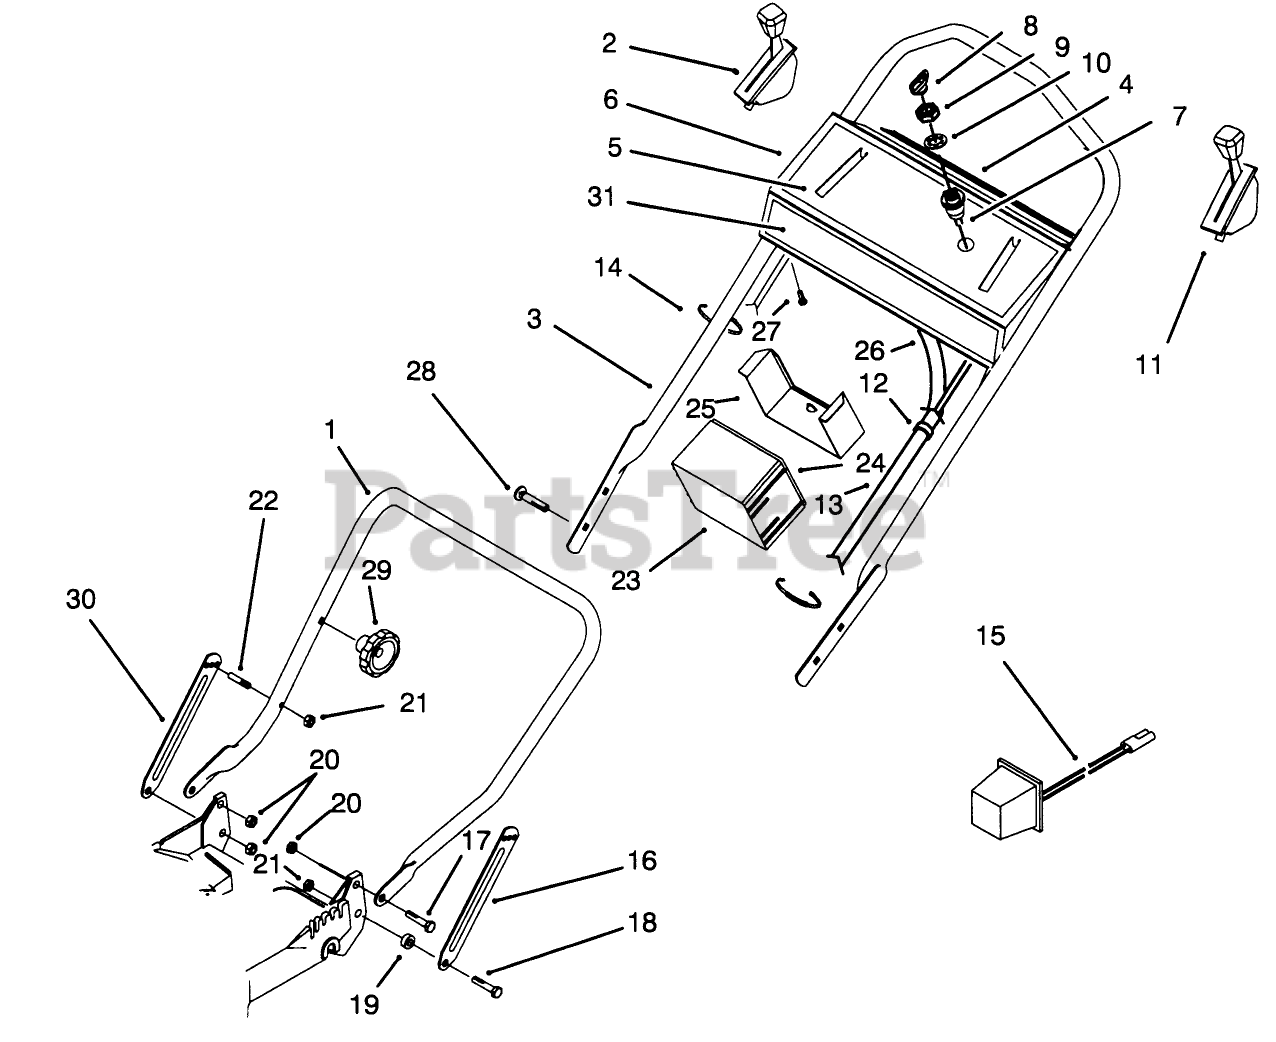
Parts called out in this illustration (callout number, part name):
2	CONTROL-SPEED, GROUND
3	UPPER HANDLE, PVC DIP
4	DECAL-PANEL, REAR
6	PANEL W/DECALS
7	STARTER SWITCH ASM
8	KEY-IGNITION
9	NUT-HH
10	WASHER-LOCK
11	THROTTLE CONTROL
12	FITTING-RING
14	TIE-CABLE
16	LH HANDLE LATCH
17	SCREW-SHOULDER
18	SCREW-SHOULDER
19	SPACER
20	NUT-LOCK, NI
21	NUT-LOCK, NI
22	HANDLE PIN
23	BATTERY ASSEMBLY,WET
24	DECAL-BATTERY
